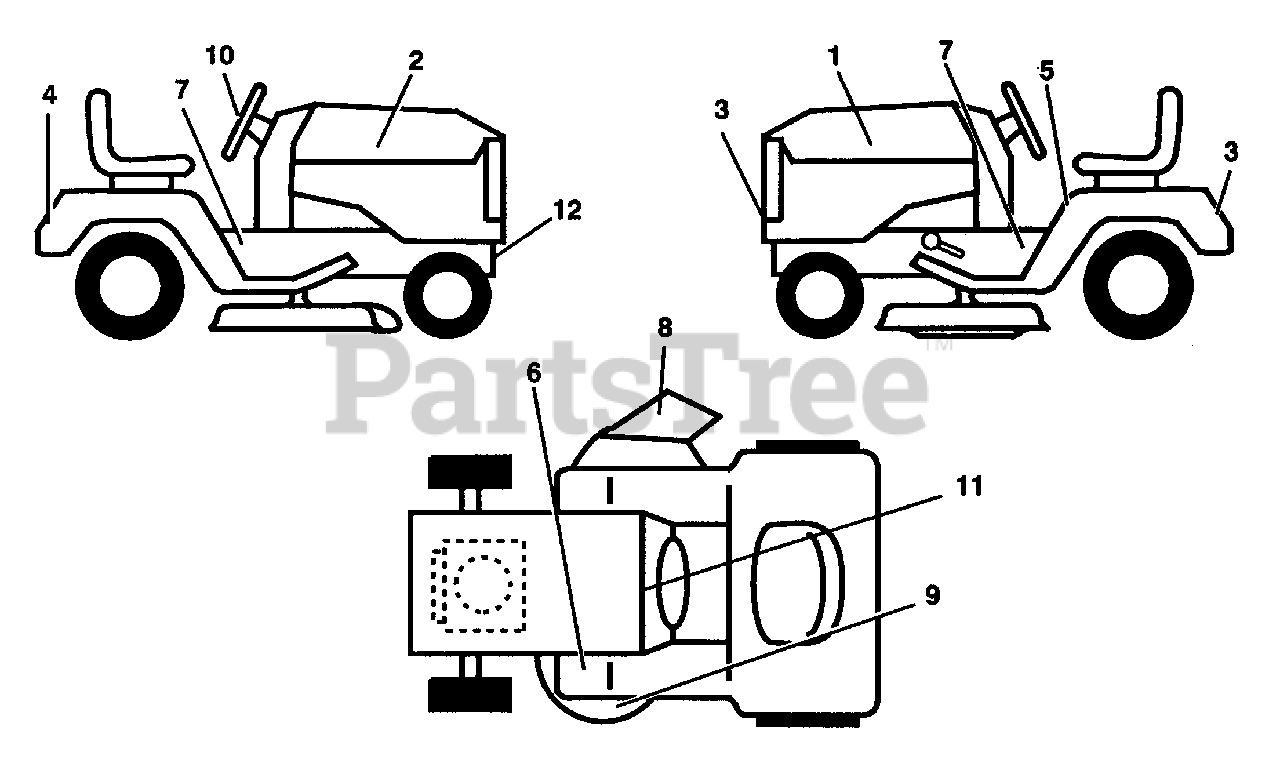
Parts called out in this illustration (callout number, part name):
1	Decal, Hood, L.H.
2	Decal, Hood, R.H. (AYP part number)
3	Decal, Grill/Fender
4	Decal, Fender (AYP part number)
5	Decal, Caution (AYP part number)
6	Decal, Clutch/Brake (AYP part number)
7	Decal, Chassis (AYP part number)
8	Decal, Danger (AYP part number)
9	Decal, Rotating Blades (AYP part number)
10	Decal, Steering Wheel Insert (AYP part number)
11	Decal, Instruction/Operating (AYP part number)
12	Decal, Adjust Belt (AYP part number)
